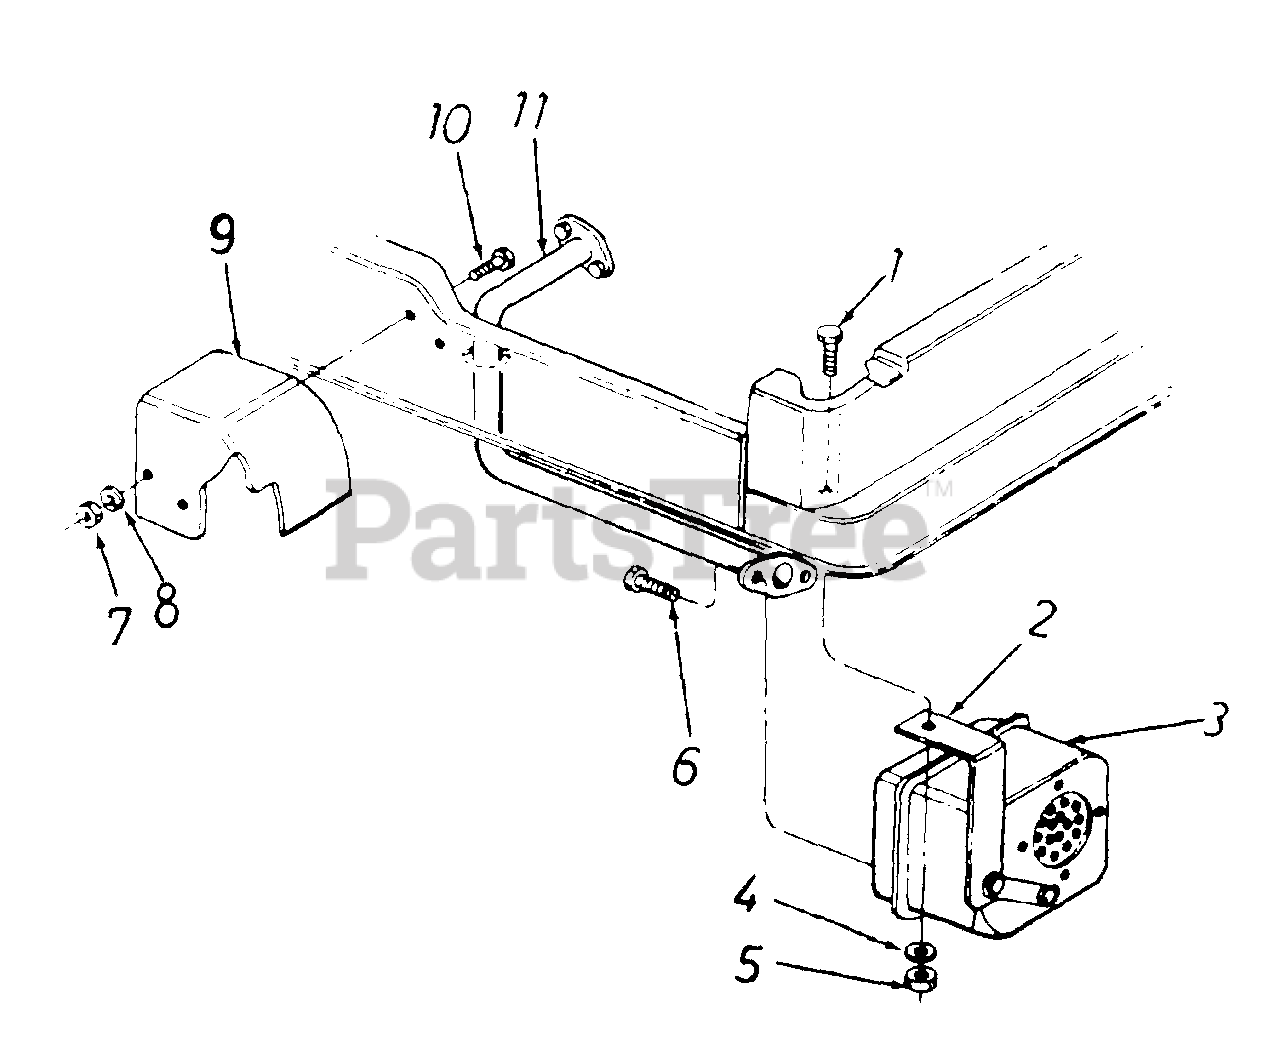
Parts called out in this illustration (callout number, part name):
1	Hex Scr. 1/4-20 x .50" Lg.
2	Muffler Strap
3	Muffler - Briggs & Stratton
4	L-Wash. 1/4 I.D.
5	Hex Nut 1/4-20 Thd.
6	Hex Scr. 1/4-20 x .50" Lg.
7	Hex Nut 1/4-20 Thd.
8	L-Wash. 1/4 I.D.
9	Exhaust Pipe Shield
10	Hex Scr. 1/4-20 x .50" Lg.
11	Exhaust Pipe Ass'y.
